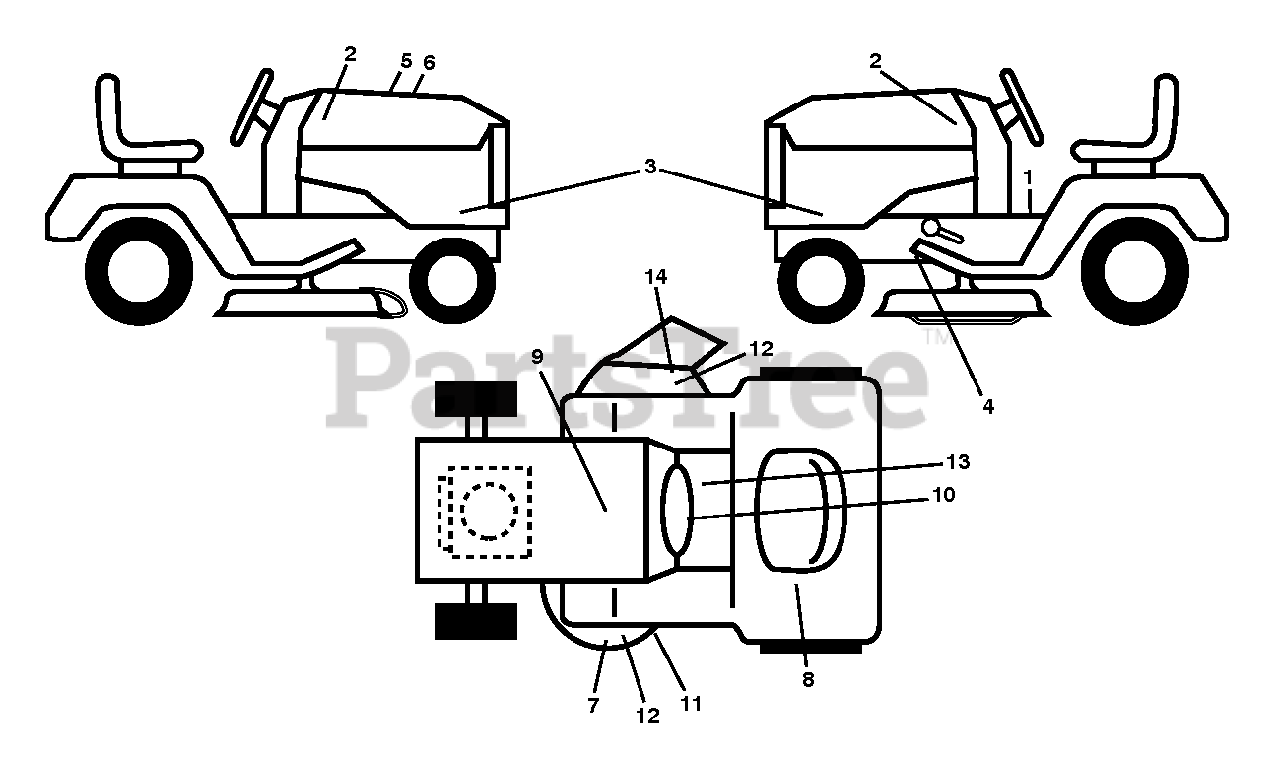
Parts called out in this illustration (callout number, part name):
1	DECAL.WARNING.2007.ENG/FR
2	DECAL.BADGE.170MM.TEXTLOGO.
3	Decal, Side Panel HUSQGT YT4
4	DECAL.PEDAL.HUSQ.CROWN
5	DECAL.WARNING.CUST.RESP.E85.
6	Decal, Replacement Kawasaki FR TLB
7	DECAL DECK DECAL DECAL.POP.LIF
8	DECAL CONTROL DECAL DECAL.RESE
9	DECAL BTRY SYMBOLS
10	DCL.WARNING.SPARK.IGNITION.CA
11	DECAL, BELT ROUTING
12	DECAL.DECK.CLEARCUT.NOSTEP
13	DECAL.FWD/REV.PEDAL.SYMBOL
14	DECAL.TRACT/ZTR.DECKWARN.HUSQ
